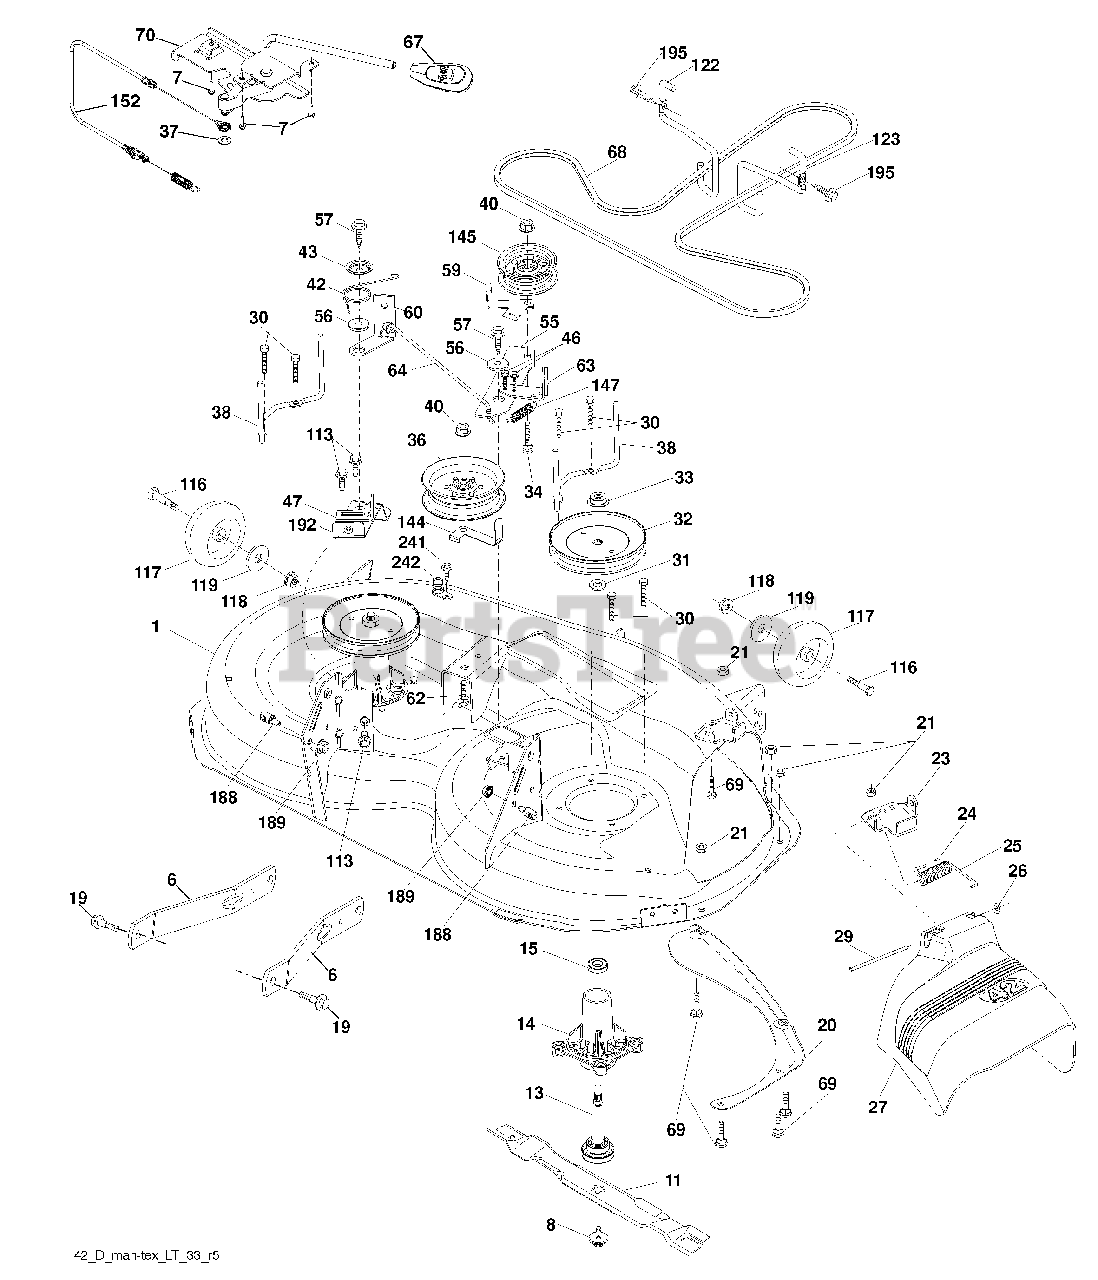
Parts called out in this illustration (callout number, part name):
1	Mower Housing
6	Arm Suspension
7	Screw #10 x 0.750 BOS Thread
8	Bolt/Washer Asm 7/16-20 unf
11	Blade, 42" Hi-Lift (For bagging or discharge)
11	Blade, 42" Mulching Premium (For better wear when mulching)
11	Blade, 42" Mulching Std (For mulching mowers only)
11	Blade, 42SP" 3N1
11	Blade, 42SP" 3N1 Premium
13	Shaft Assembly, Mandrel
14	Housing, Mandrel
15	Bearing, Ball, Mandrel
19	Bolt, Shoulder
20	Baffle, Vortex
21	Nut, Crownlock 5/16-18 unc
23	Bracket, Deflector
24	Cap, Sleeve
25	Spring, Torsion, Deflector
26	Nut, Push
27	Shield, Deflector
29	Rod, Hinge
30	Screw Thdrol Rolling Wsh Hd
31	Washer, Spacer
32	Pulley, Mandrel
33	Nut, Toplock, Flanged
34	Bolt Carr Sh. 3/8-16 x 1-1/2 Gr. 5
36	Pulley, Idler 4.50 RAW
37	Washer 13/32 x 13/16 x 16 Ga.
38	Keeper Belt Mandrel
40	Nut, Lock Flg. 3/8-16 unc
42	Spring Torsion Brake
43	Spring Torsion Retainer
46	Screw Thd Roll 1/4-20 x 5/8
47	Bracket Clutch Cable
55	Arm, Idler
56	Spacer, Retainer
57	Screw Hexwsh Thd 3/8-16 x 1
59	Guard, Tuv Idler (94)
60	Arm Brake Mower
62	Bolt Rdhd Sqnk 3/8-16 unc x 2
63	Arm Brake Mower
64	Linkage Brake
67	Handle, Clutch Cable
68	V-Belt
69	Bolt Rdhd Sqnk 5/16-18 x 5/8
70	Clutch Asm. Manual
113	Screw 5/16-18
116	Bolt
117	Wheel Gauge
118	Nut Lock 3/8-16 unc
119	Washer 3/8-7/8 x 14 Ga.
122	Keeper Belt Eng. LH
123	Keeper Belt Eng. RH
144	Keeper Belt
145	Pulley Idler Primary
147	Spring Return
152	Cable Clutch Manual w/Spr.
188	Stud Fastener
189	Nut Lock Hex Flange
192	Bracket Brake Stand LH
195	Screw Hexwsh Thdr 3/8-16 x 3/4
241	Screw
242	Washout Port
242	coupling Quick Connect
242	Mandrel Assembly
242	Replacement Mower, Complete
